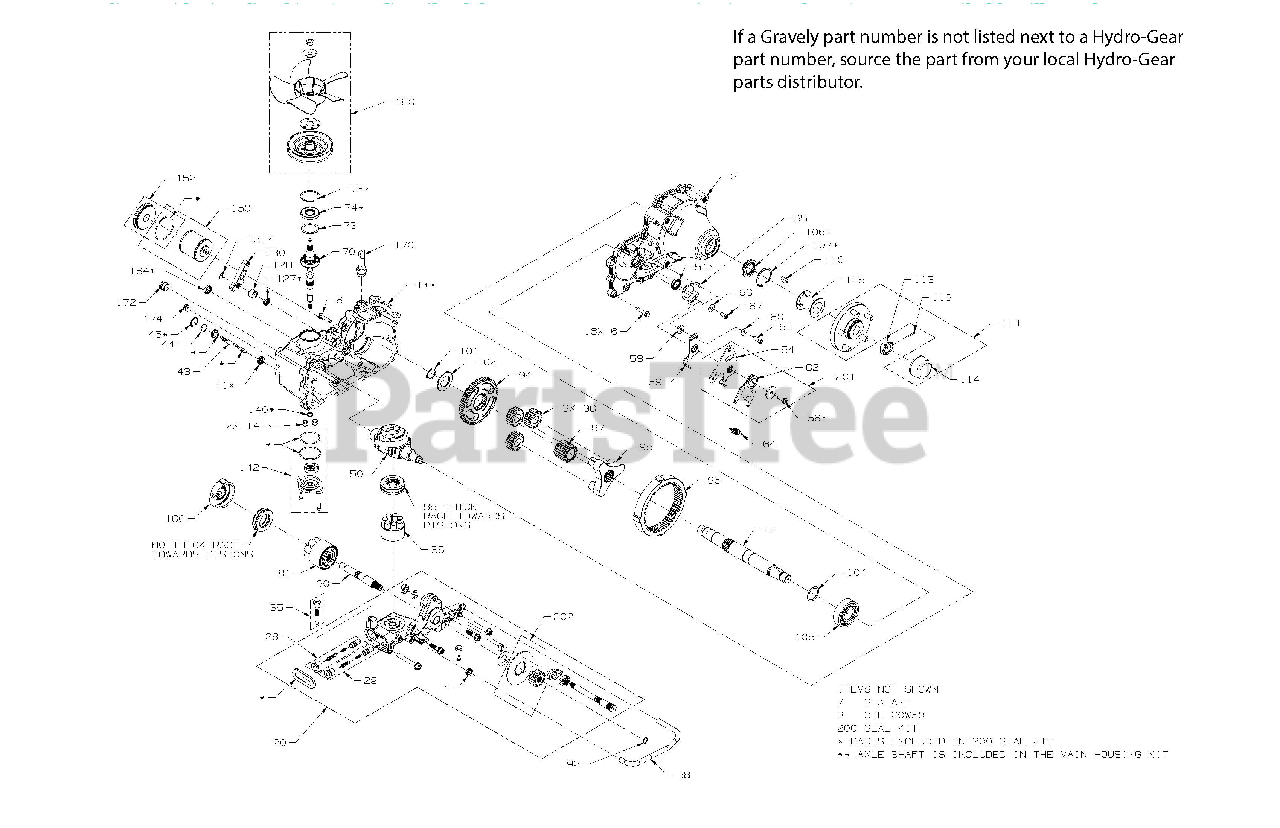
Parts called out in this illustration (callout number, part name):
1	KIT, HOUSING, MAIN, LH
2	KIT, HOUSING, SIDE, LH
7	SEALANT TUBE 10.1OZ.
20	CENTER SECTION L(03935300)
28	HG SHOCK VALVE KIT
29	HG SHOCK VALVE KIT
35	HG CHARGE RELIEF VALVE KIT
38	TUBE, FILTER, LH
41	SEAL, LIP 12 X 24 X 5 TC
43	ASSEMBLY, ACTUATOR BYPASS
44	SPRING, WAVE
50	SWASHPLATE, 16CC, MACHINED
54	ARM, CONTROL, LH
56	TWHCS 5/16-24 X 1.00
58	SPACER
59	ARM, NEUTRAL LEFT
60	WASHER
61	SHCS 5/16-24X1 PATCH
62	ASSEMBLY, RTN, UNI-DIRECTIONAL
64	RTN SPRING HG 51605
65	PLATE, STOP, LH
66	WASHER
70	INPUT SHAFT HG 71941
74	SEAL, LIP 25 X 52 X 7 TC
75	RING, RETAINING, INTERNAL
80	BRG, THRUST (21) 42X68X16, PLASTIC CAGE
81	KIT, MOTOR BLOCK
86	KIT, BLOCK, 16CC CYLINDER
90	SHAFT, MOTOR
92	RING, RET 62 EXT
98	CARRIER
100	BALL, .75
102	SPACER, THRUST, AXLE
105	BEARING,BALL 35 X 80 X 21 6307
106	HG SEAL LIP 1.375X2.062X.250
107	RING, RETAINING
110	KEY, WOODRUFF 5/16 X 1
111	HG 5 BOLT HUB KIT
113	HG HEX NUT 1-20 SLOTED
114	CAP, AXLE
116	PIN, COTTER 9/64 X 2 EXTENDED
127	SEAL- LIP .562X.875X.187
130	BRAKE ARM HG 53018
131	RING, RETAINING
140	SEAL, .50 X .69 X .09 VC
141	TUBE, PUSH O-RING
142	CHARGE COVER KIT
150	FILTER,HYD OIL W/ORING ZT-54OO
152	HG FILTER PLUG KIT
160	PLATE, MOTOR, SWASH
164	SEAL, PLUG
170	FITTING, 7/8-14 SAE, .625 BEADED
172	PLUG, 7/8-14, METAL
174	PLUG, 9/16-18, METAL
180	PULLEY/FAN KIT HG 71906
200	SEAL KIT HG 71945
201	KIT, RTN, LH, UNI-DIRECTIONAL
202	KIT, BRAKE ROTOR, GEAR
